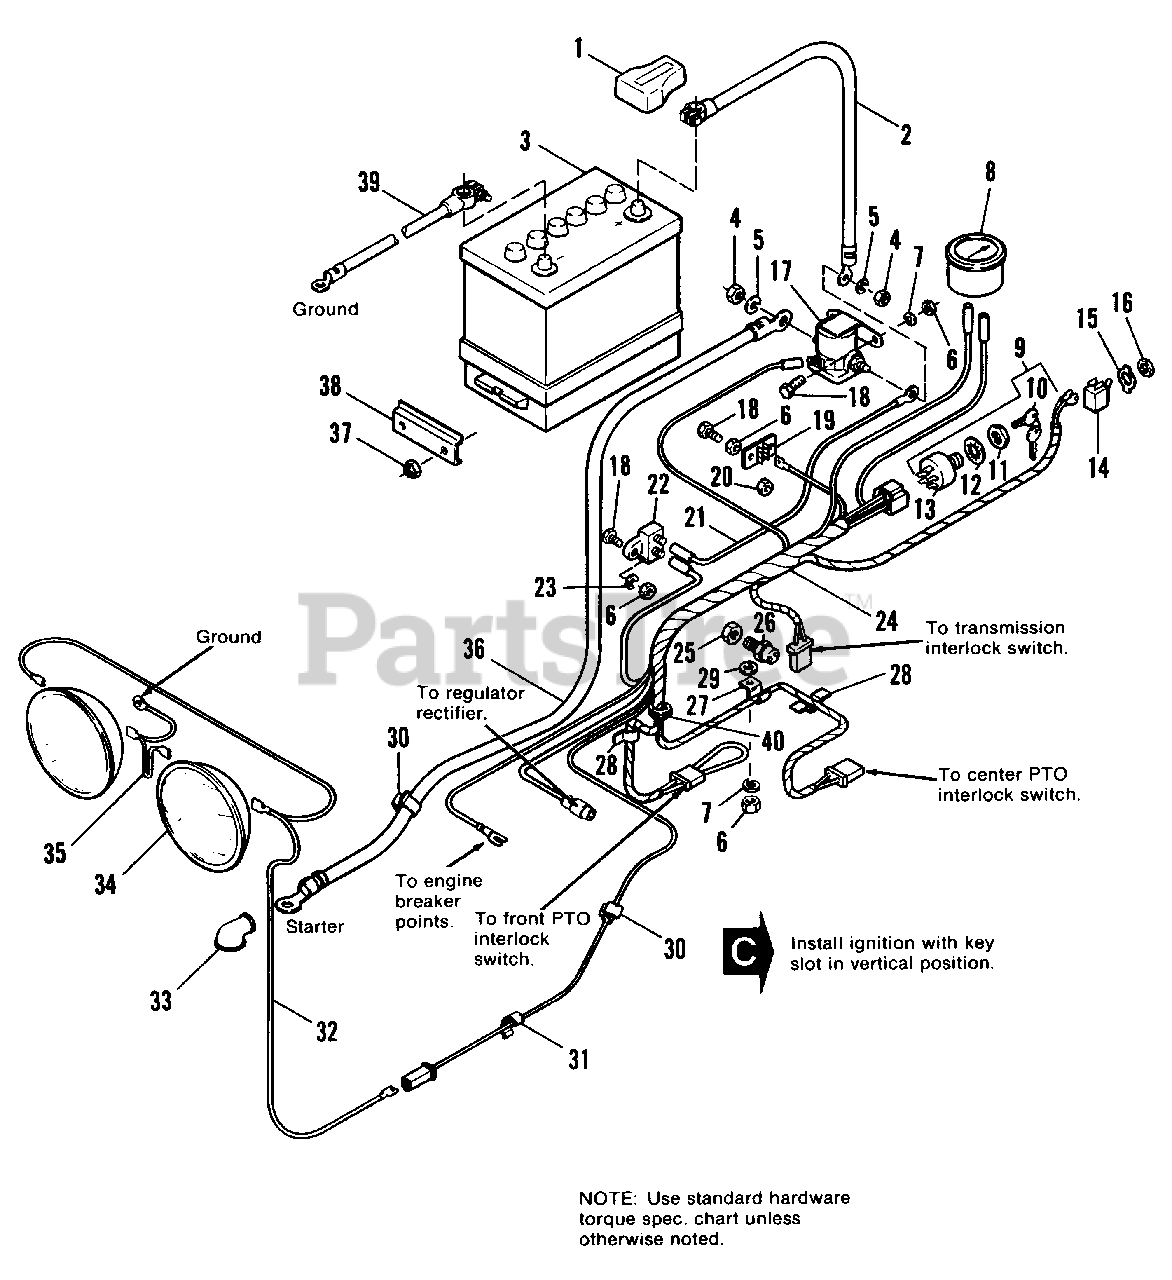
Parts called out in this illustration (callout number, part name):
1	PROTECTOR, Terminal
2	CABLE, Battery to Solenoid
3	BATTERY (Includes Decal)
4	NUT, Hex, 5/16-18
5	LOCKWASHER, 5/16
6	NUT, Hex, 1/4-20
7	LOCKWASHER, 1/4
9	SWITCH & KEY ASSY., Ignition
11	NUT, Special
12	LOCKWASHER, Internal Tooth, 5/8
14	SWITCH, Toggle
16	NUT, Switch
17	SOLENOID, Starter
18	CAPSCREW, Hex Hd., 1/4-20 x 5/8
19	BOARD, Terminal
20	LOCKNUT, Hex, 1/4-20
22	CIRCUIT BREAKER
23	LOCKWASHER, 1/4
24	HARNESS ASSY.
25	NUT, Pal
26	SWITCH, Interlock
27	CLIP, Cable
28	CLIP, Wire
29	WASHER, Cup
30	CLIP, Tinnerman
31	CLIP, Tinnerman
33	COVER, Terminal
35	Wl RE ASSY.
36	CABLE, Solenoid to Starter
37	NUT, Elastic, 5/16-18
39	CABLE, Battery to Ground
